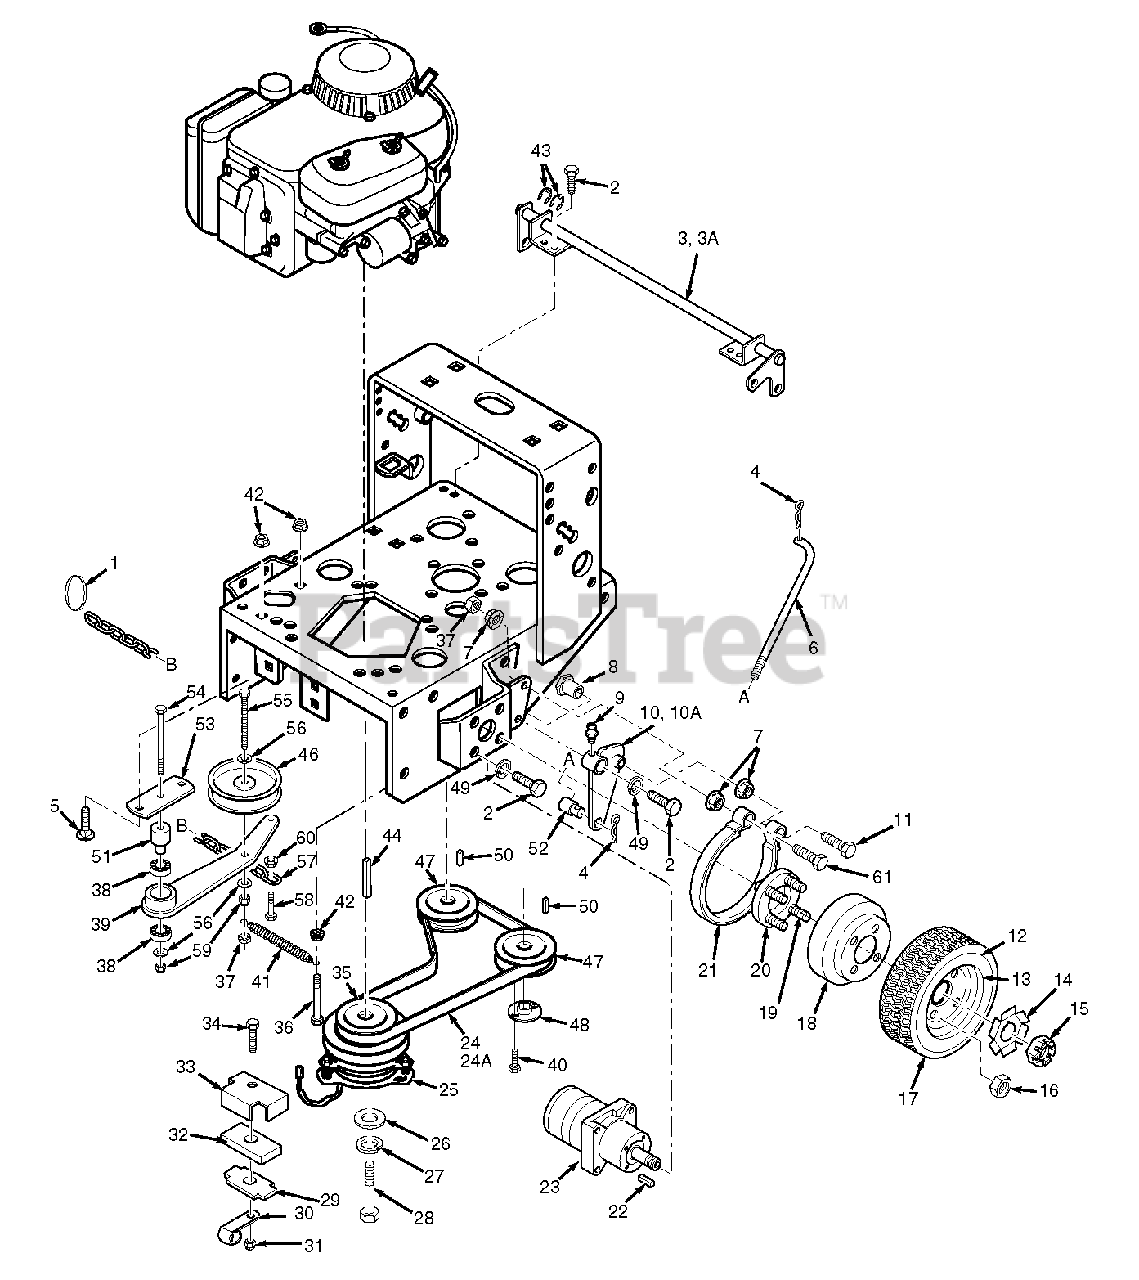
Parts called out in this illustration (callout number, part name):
1	Ring, Split
2	Bolt, 3/8-16 x 1" Hex Head
3	Brake Shaft Assembly Weldment, 16" Small Frame
3A	Brake Shaft Assembly Weldment, 20" Large Frame
4	Hair Pin Cotter, .094 x 1.62
5	Carrage Bolt, 5/16-18 x .75"
6	Rod, Brake Lower
7	Nut, 3/8-16 Serr. Flange
8	Bushing, Brake
9	Grease Fitting
10	Brake Actuator Weldment-LH
10A	Brake Actuator Weldment-RH
11	Bolt, 3/8-16 x 2-1/4"
12	Tire, 16 x 6.50, 4 ply
13	Rim Assy
14	Lock Washer, Wheel Motor
15	Hex Castle Nut, 3/4-28 UNEF
16	Nut, Lug
17	Wheel Assy.,
18	Brake Drum
19	1/2-20 Serrated Bolt
20	Hub, Wheel
21	Brake Band, 7.5"
22	Key, 3/16 X .75 Woodruff
23	Wheel Motor
24	Belt, Pump Drive, 16" Small Frame
24A	Belt, Pump Drive, 20" Large Frame
25	Electric Clutch
26	Flat Washer .469 x 1.75 x .25
27	Lock Washer, 7/16"
28	Hex Head Bolt, 7/16-20 x 2-3/4"
29	Plate, Backing
31	Nut, 5/16-18 Elastic Stop
32	Rubber Pad, Clutch Stop
33	Retainer, Clutch Stop
34	Hex Head Bolt, 5/16-18 x 1.75"
35	Pulley, Pump Drive Engine
36	Hex Head Bolt, 5/16-18 x 2.75"
37	Nut, 3/8-16 Center Lock
38	Ball Bearings
39	Idler Arm Weldment, Pump
40	Bolt, Hex Head 1/4-20 x 1" Grd 8
41	Spring, Pump Belt Idler
42	Nut, 5/16-18 Serr. Flange
43	Retaining Ring, 3/4" Ext. "E"
44	Key, 1/4x1/4 x 3.75"
45	Flat Washer, 3/8"
46	Pulley, Idler 4.5"
47	Pulley, Pump Shaft
48	Tapered Hub
49	Lockwasher, 3/8"
50	Key, 5.0 x 5.0 x 25mm
51	Pivot, Idler (Long)
52	Swivel Joint
53	Base, Idler Pivot
54	Bolt, Hex Head 3/8-16 x 3"
55	Bolt, Hex Head 3/8-16 x 2.75"
56	Flatwasher 3/8"
57	Chain
58	Bolt, Hex Head 1/4-20 x 1.25"
59	Nut, Hex Elastic Stop 3/8-16
60	Nut, Serrated Flange 1/4-20
61	Bolt, Hex Head 3/8-16 x 2.63"
